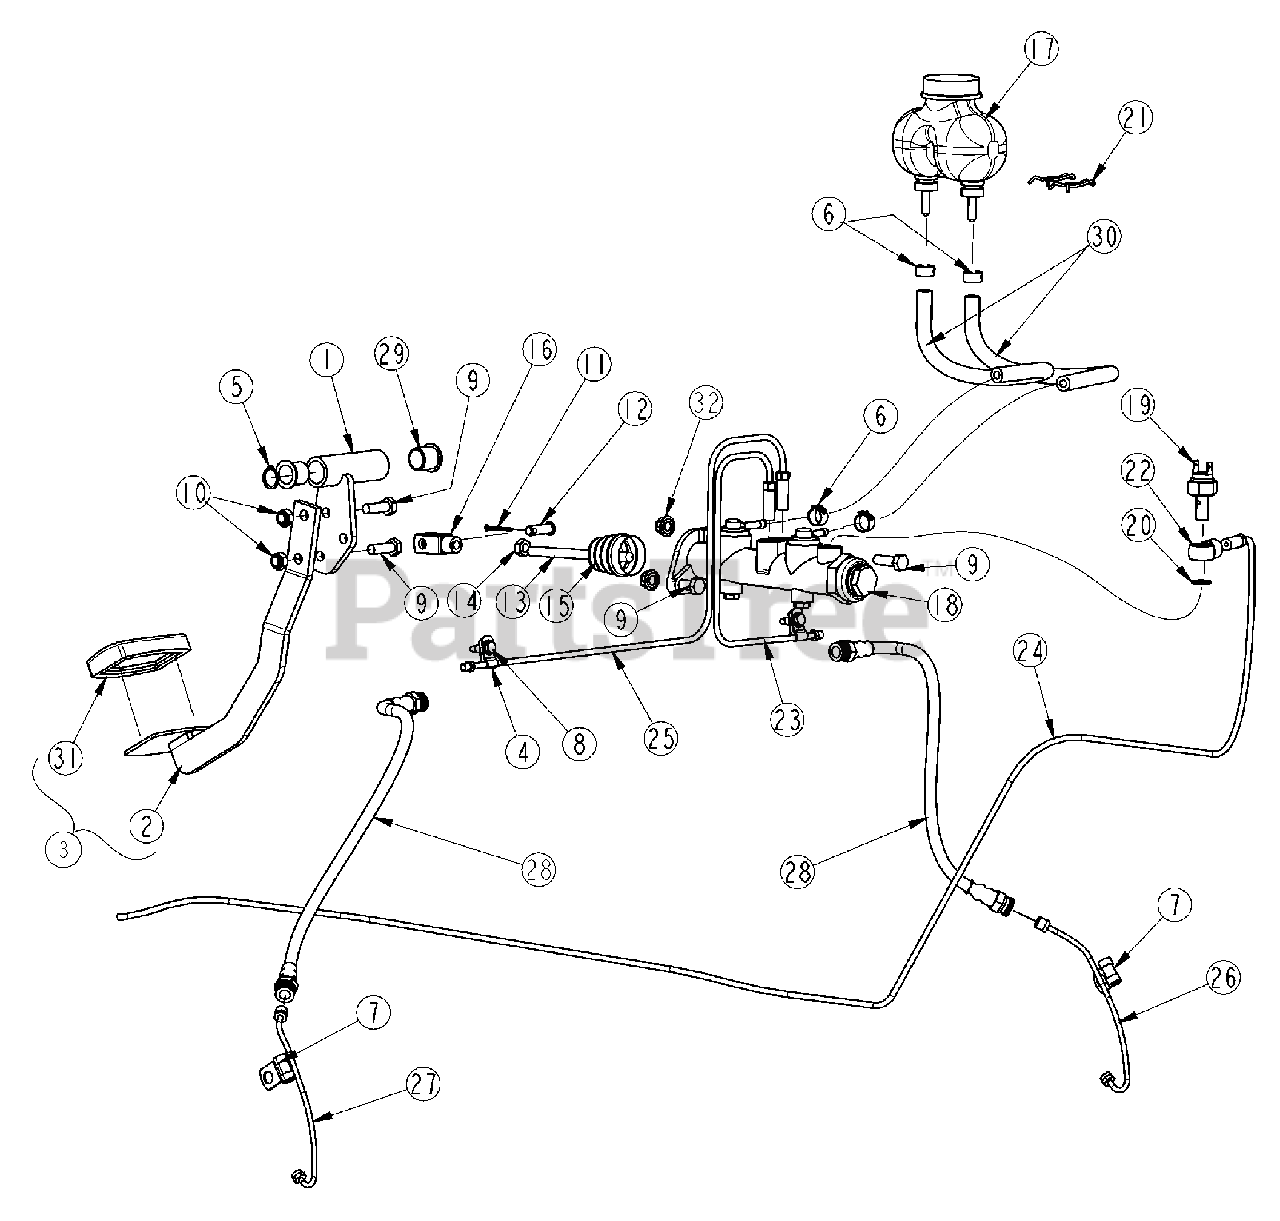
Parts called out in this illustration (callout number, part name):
1	BRAKE PEDAL PIVOT WELDMENT
2	BRAKE PEDAL ARM WELDMENT
3	BRAKE PEDAL W/PAD ASSEMBLY
4	WIRING/TUBE CLIP FOR 1/4 OD
5	RETAINING RING 5/8 EXT.
6	CLAMP PINCH FOR .50 OD HOSE
7	HOSE CLAMP 1/4 ID
8	HH DRILL SCREW 1/4 x 3/4 LG
9	BOLT, HEX 5/16-18 x 1 GR5 YELLOW ZINC
10	NUT, HEX NYLOCK .312-18
11	PIN, COTTER 3/32 x 1
12	PIN, CLEVIS 5/16 x 1
13	MASTER CYLINDER PUSH ROD
14	JAM NUT MASTER CYL. PUSH ROD
15	MASTER CYLINDER BOOT
16	MASTER CYLINDER CLEVIS
17	DUAL RESERVOIR BRAKE FLUID W/CAP
18	DUAL MASTER CYLINDER
19	MASTER CYLINDER PRESS. SWITCH
20	MSTR CYL CPPR WSHR 16X10X1.5MM
21	MASTER CYLINDER RESERVOIR CLIP
22	BULK HEAD FLOW THROUGH
23	FRONT BRAKE LINE LH
24	ST STEEL BRAKE LINE
25	FRONT BRAKE LINE 21 1/4 RH ST
26	FRNT BRAKE LINE END LH STEEL
27	FRNT BRAKE LINE END RH STEEL
28	BRAKE LINE RBR 17" M10 x 1 FEMALE
29	BUSHING 3/4 OD x 5/8 ID x 3/4 FLG HD
30	12.5" FUEL LINE/HYDRAULICFLUIDRESVOIR.
31	BRAKE/ACCELERATOR PEDAL RUBBER
32	NUT, TOP LOCK FLANGE .31-18
